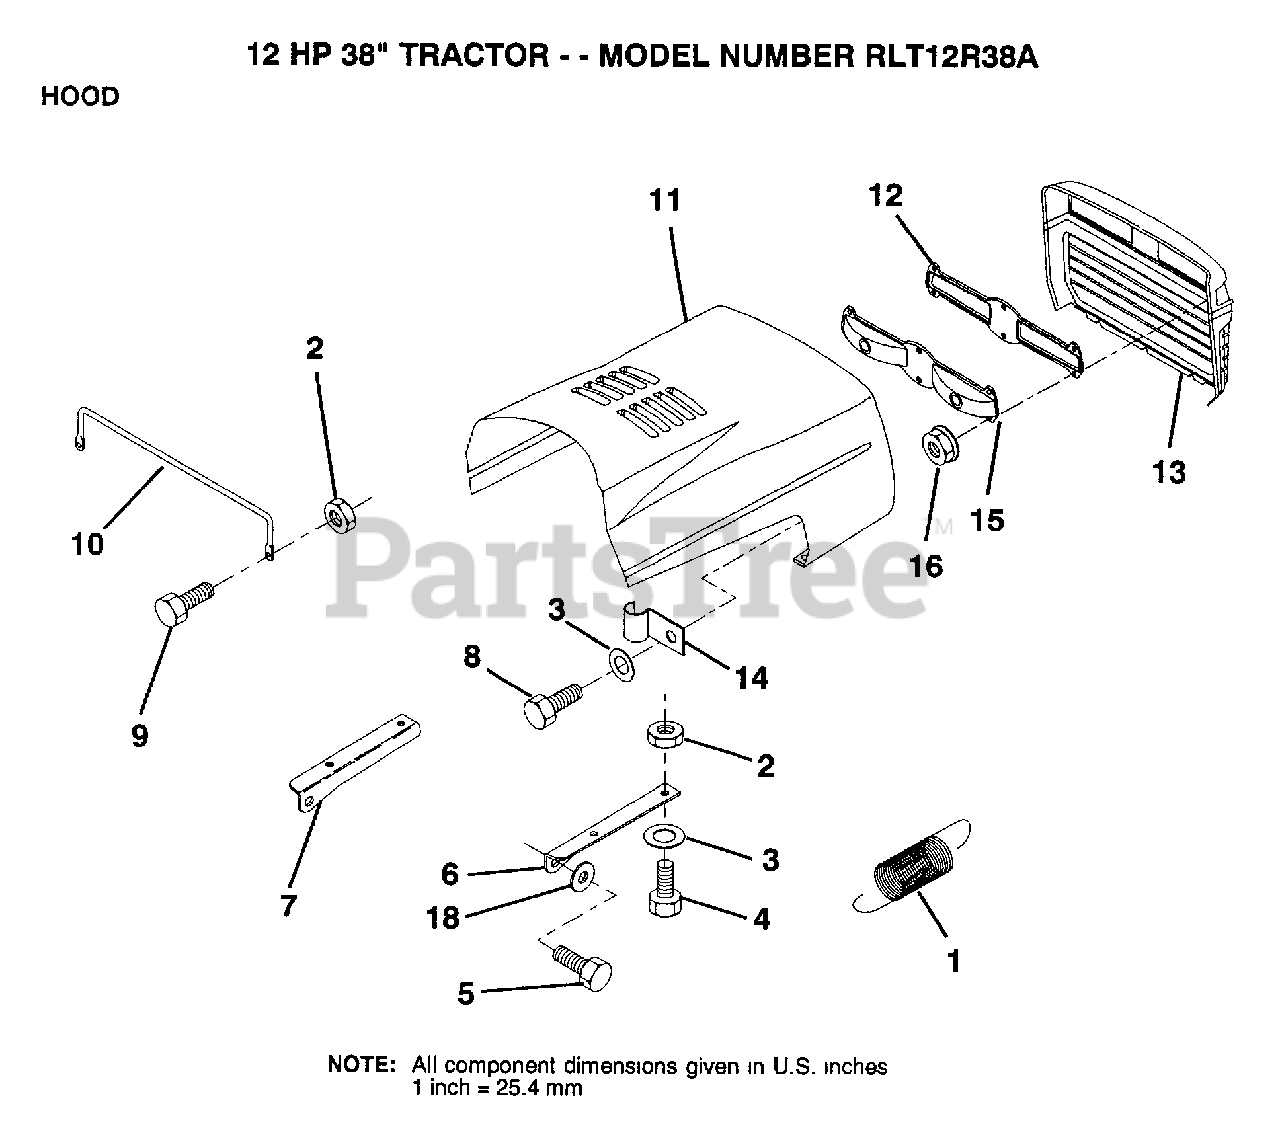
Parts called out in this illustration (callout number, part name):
1	EXT SPRING
2	NUT
3	WASHER
4	BOLT
6	BRKT HOOD RH
7	BRKT HOOD LH
10	"BRACE,HOOD"
14	CLIP T
18	WASHER
